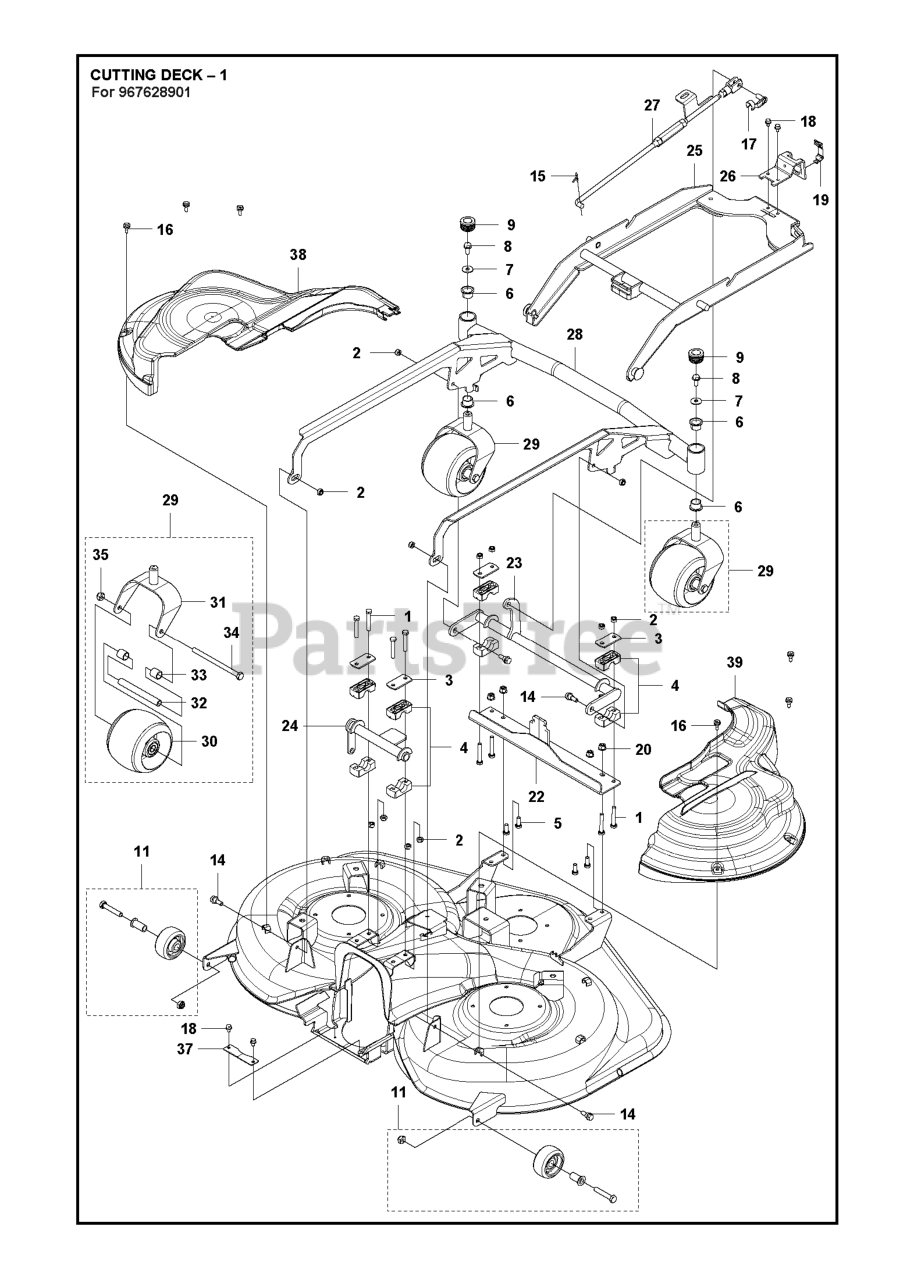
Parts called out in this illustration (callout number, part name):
2	LOCKNUT M8
20	NUT FLANGE
29	PIVOT WHEEL ASSY
30	DECK ROLLER, FRONT
35	NUT
